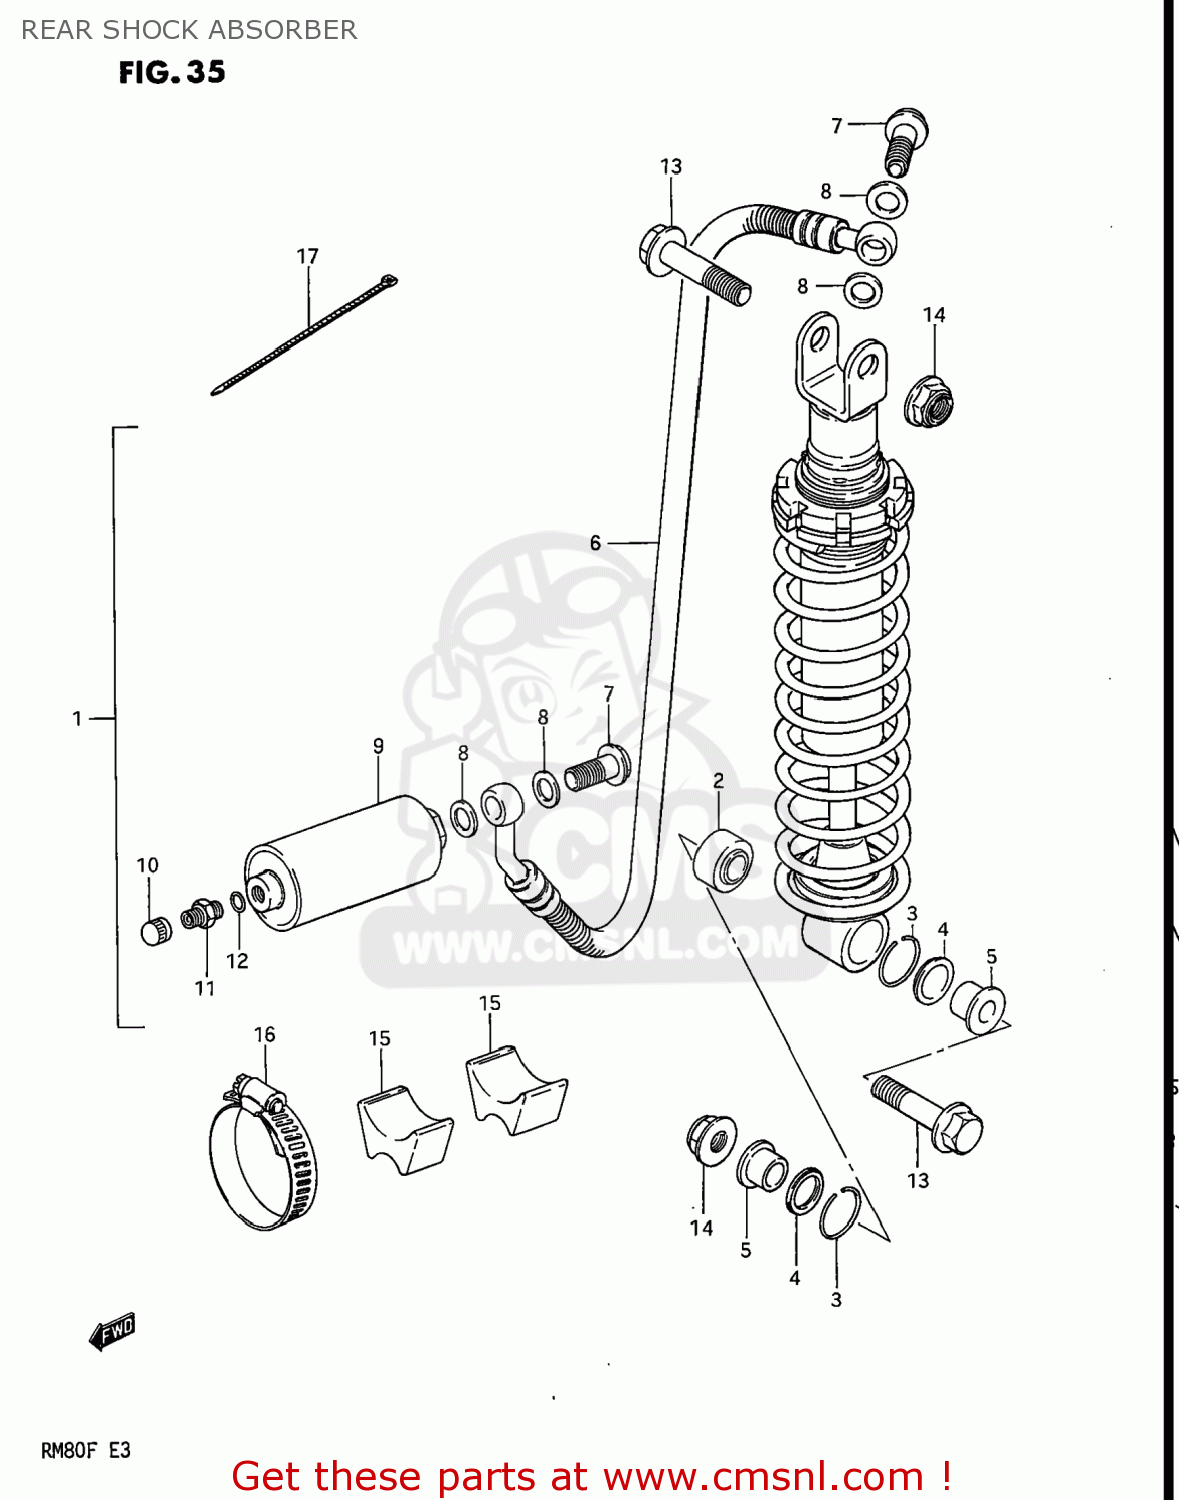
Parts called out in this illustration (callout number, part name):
1	ABSORBER ASSEMBLY,REAR SHOCK
2	BEARING
3	RING
4	DUST SEAL
5	SPACER
6	HOSE,REAR SHOCK ABSORBER
7	BOLT,REAR SHOCK ABSORBER
8	WASHER(10X15X1.5)
9	RESERVE TANK,REAR SHOCK
10	CAP,VALVE AIR
11	VALVE,FRONT FORK AIR
12	O-RING (D:3.8 ID:19)
13	BOLT(10X50)
14	NUT
15	CUSHION,REAR SHOCK ABSORBER
16	CLAMP
17	CLAMP
